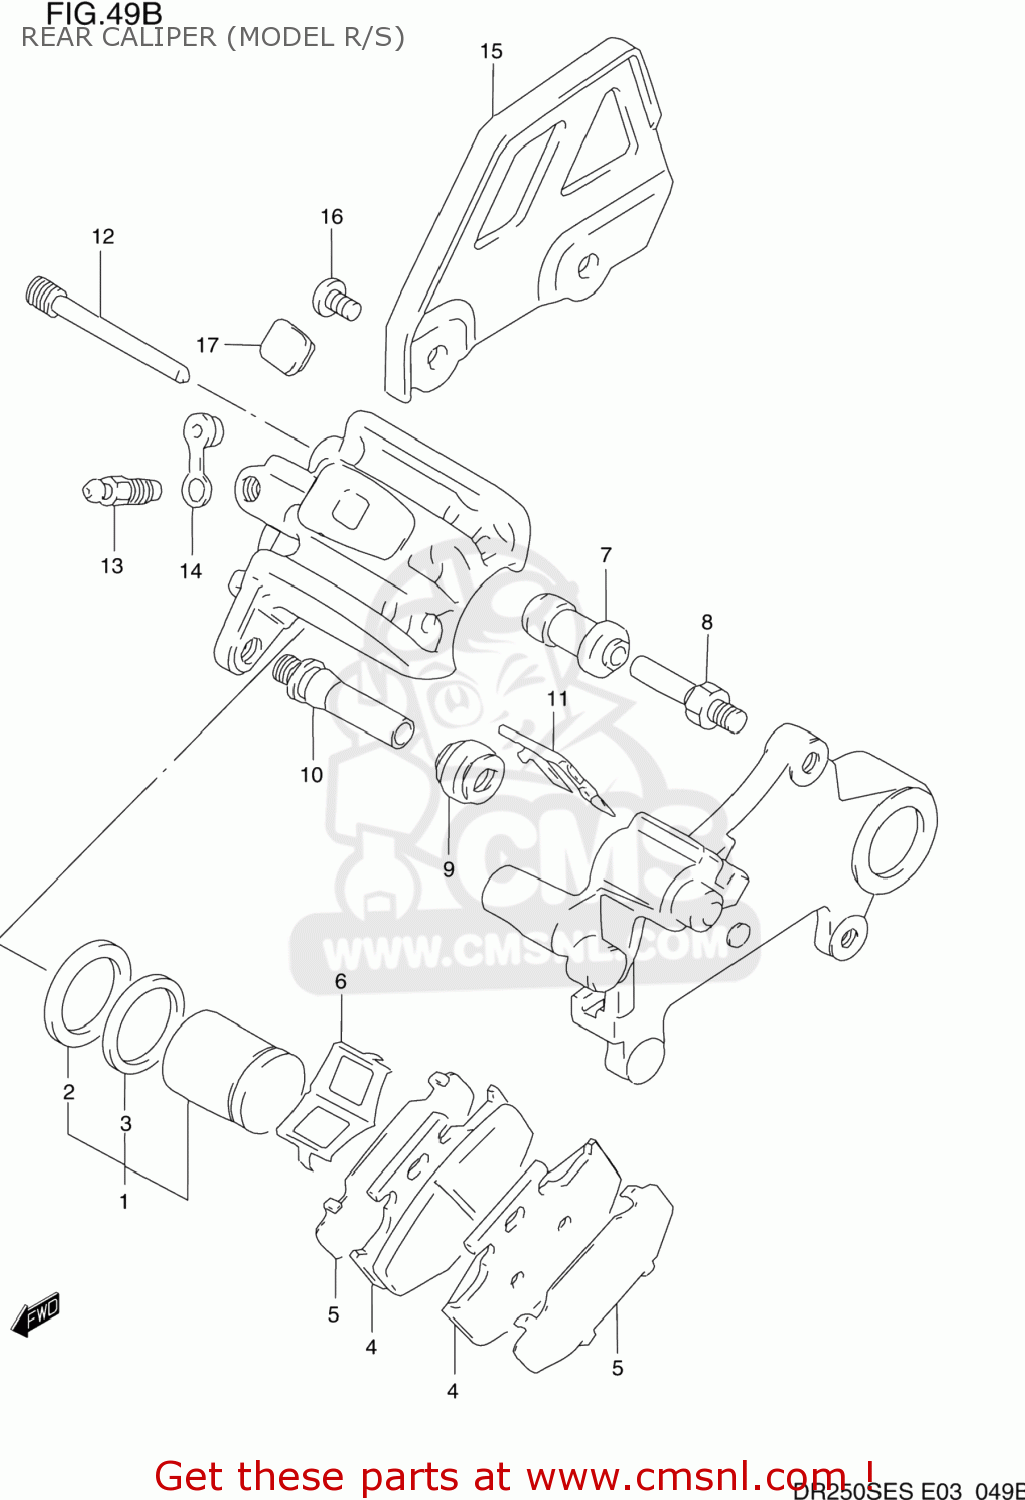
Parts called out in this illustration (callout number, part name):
1	PISTON SET
2	SEAL,PISTON
3	SEAL
4	PAD (MCA)
5	SHIM
6	SPRING,PAD
7	BOOT
8	PIN,BOLT
9	BOOT
10	PIN
11	RETAINER,BRACKET
12	PIN,HANGER
13	BLEEDER
14	CAP,BLEEDER
15	GUARD,RR CALIPER
16	SCREW 6X12
17	COVER,RR CALIPER BODY
